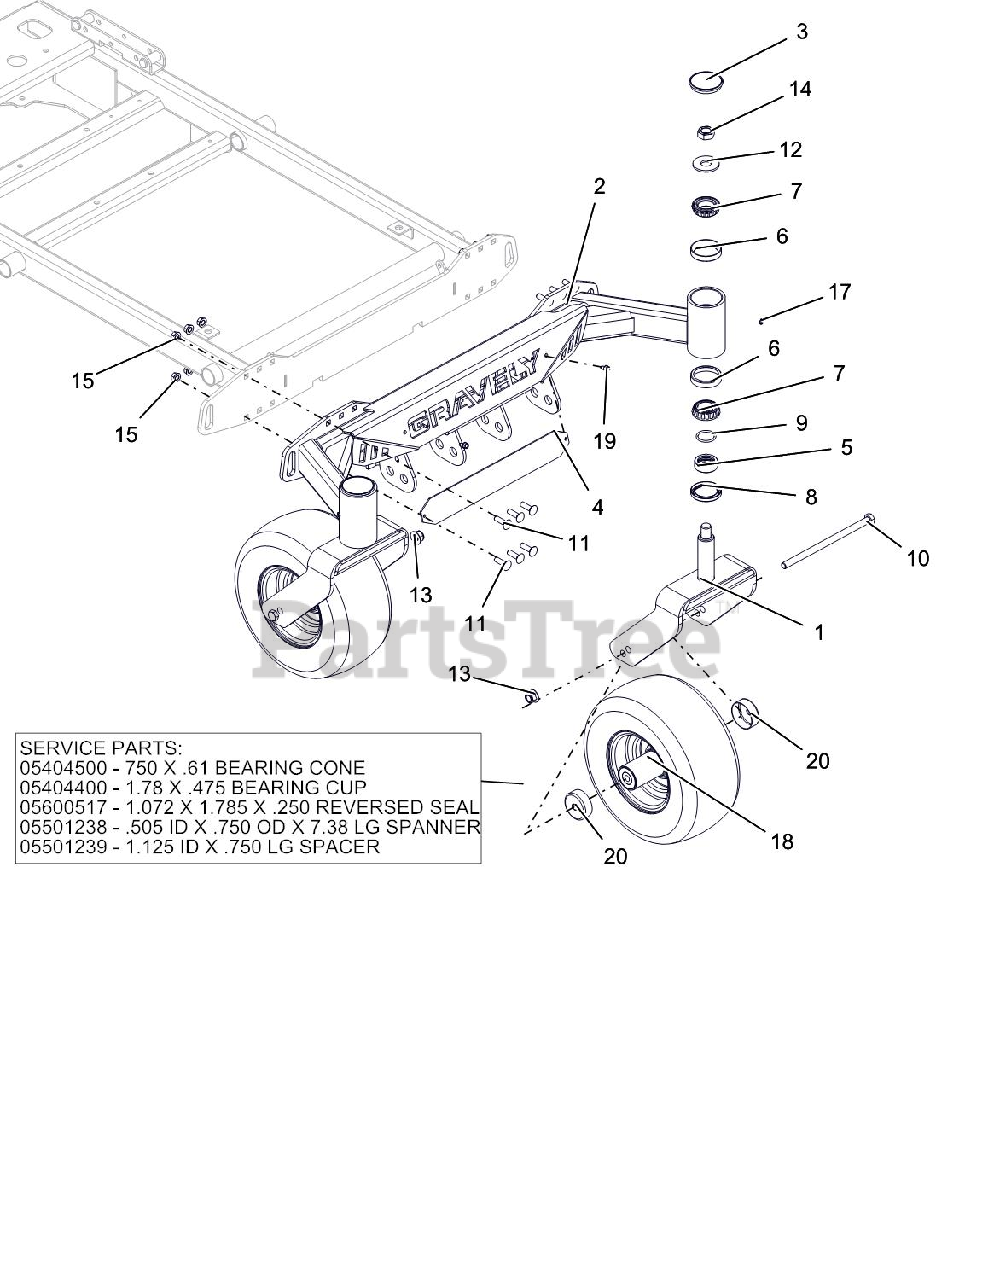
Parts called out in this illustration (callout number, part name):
1	WMT, CASTER FORK - RED
2	WLDMT, FRONT 60 AXLE
3	CAP, DUST
4	PLATE, BACK NAME-BLACK
5	SPCR, FRONT CASTER FORK
6	BRG, CUP 2.328 X .465
7	BRG, CONE 1.250 X .660
8	SEAL, OIL 1.75 X 2.332 X .312
9	O-RING, .139 W X 1.234 ID
10	BLT-HEX .50-13X9.00 GR5 YWZC
11	BLT-RDHDSQNK .38-16X1.25 G5 YWZC
12	WSHR-FL-STL.812X2.00X.148YWZC
13	NUT-LK-NYL-FLG .50-13 YWZC
14	NUT-LK-TOP-JAM .75-16 YWZC
15	NUT, LK-TOP-FLG .38-16 YWZC
17	FITTING, .250-28 FLUSH MOUNT GREASE
18	TIRE/WHEEL, 13X6.50-6
18	1.125 ID X .750 LG SPACER
18	750 X .61 BEARING CONE
18	1.78 X .475 BEARING CUP
18	1.072 X 1.785 X .250 REVERSED SEAL
18	.505 ID X .750 OD X 7.38 LG SPANNER
19	SCR-TAP .25-20X.50 HWH TR YWZ
20	SHIELD, WHEEL BEARING
